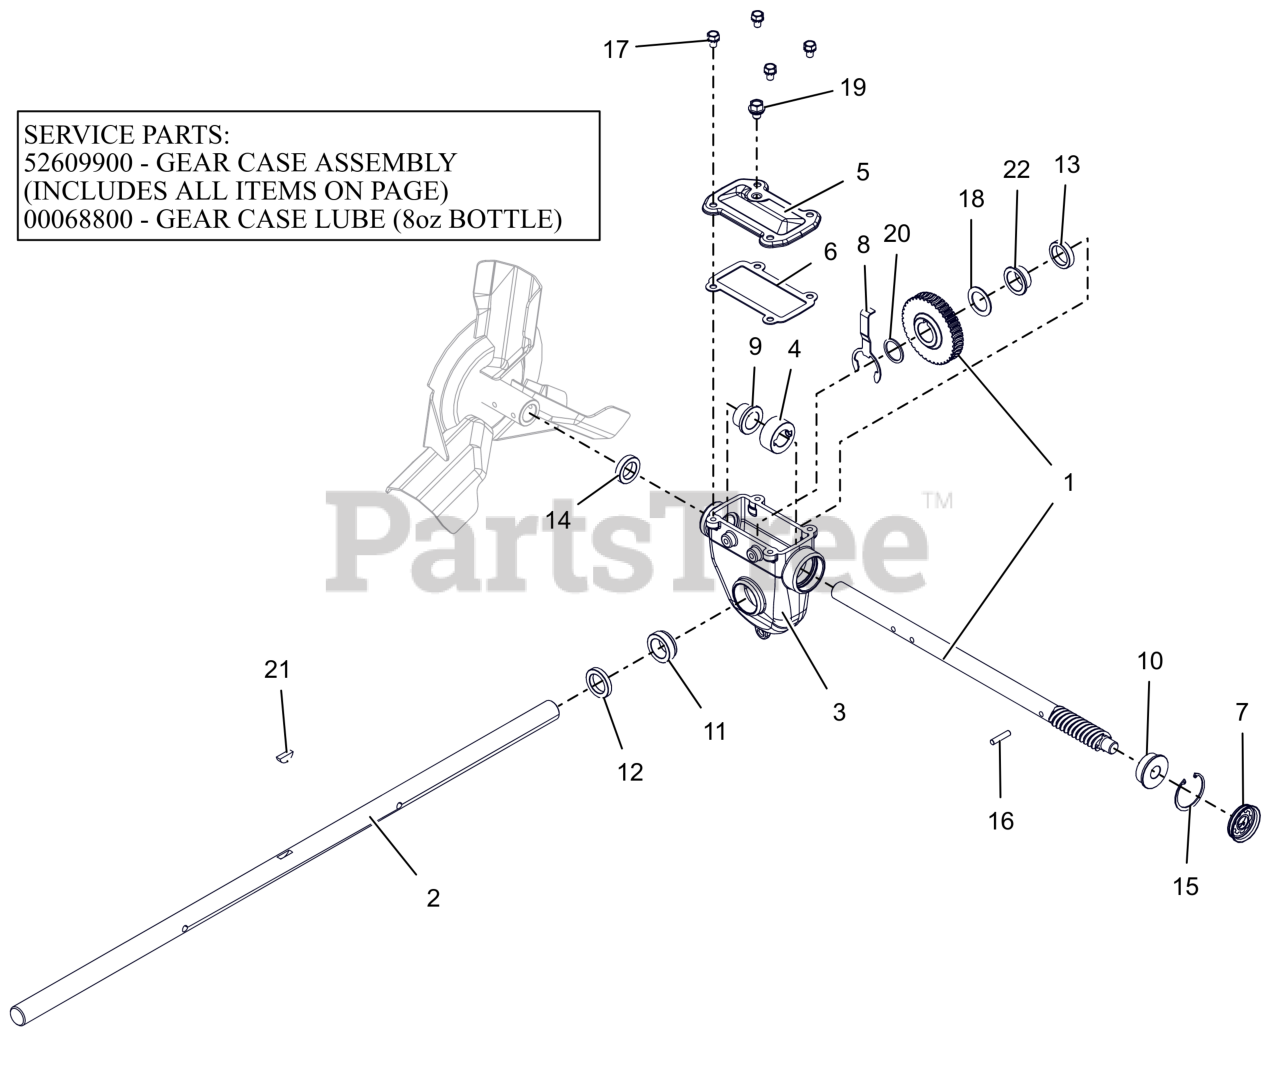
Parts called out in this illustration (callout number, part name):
1	ASSY, WORM SHAFT & GEAR
2	SHAFT, RAKE-36"
3	GEARCASE, LARGE MACHINED
3	GEAR CASE, 36" IRON PRO TOP-LD
3	ARIENS L3 LUBE, 8 OZ BOTTLE
4	THRUST COLLAR, .875"ID SLIPFIT
5	COVER, TOP - LARGE IRON
6	GASKET, TOP - LARGE GEARCASE
7	COVER, GEAR CASE 1.75"
8	BUSHING RETAINER, LARGE
9	BSHG-FLG .879X1.128X.75X1.45
10	BSHG-FLG .628X1.503X.58X1.725
11	BSHG-FLG LARGE, RIGHT
12	SEAL-OIL .999X1.500X.250 TBC29
13	SEAL-OIL .999X1.375X.312 TBC29
14	SEAL-OIL .873X1.375X.312 TBC29
15	RG-RTNG-INT 1.750X.062
16	PIN-STR .250X1.12 6150
17	BLT, SEMS .31-18X.50 G5 ZCC
18	WSHR, FLT 1.010X1.505X.062 ZCC
19	SCR, .380-15X.500 W/SEAL WASHER
20	WSHR, FLT 1.010X1.250X.068 ZCC
21	KEY-WDRF .25X.875 HRD #A
22	BSHG-FLG 1.006X1.128X.555X1.45
